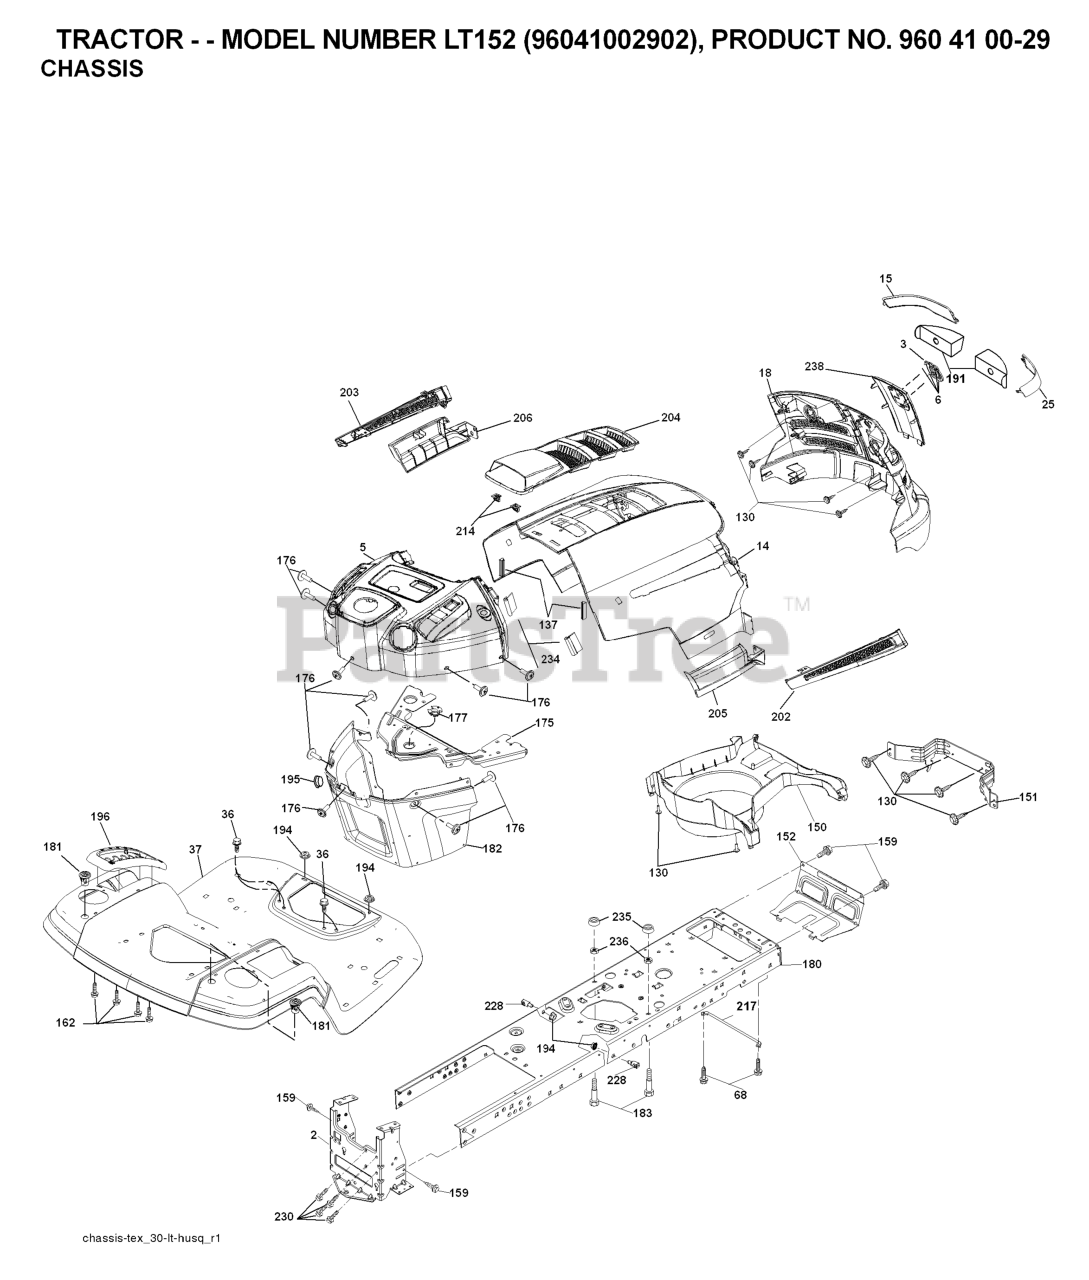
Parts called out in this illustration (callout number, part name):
2	DRAWBAR.1PC.NSTL
3	RP LOGO
5	DASH
14	HOOD
15	LENS.HUSQVARNA LT.LH
18	RP GRILLE/LENS ASM.
25	LENS.HUSQVARNA LT.RH
36	SCREW 5/16"
68	Screw 5/16-18 x 1/2 Hex, Self Tapping 5/16-18 x 1/2
130	SCREW
137	BUMPER DASH
151	BRACKET PIVOT
152	SHIELD.BROWNING/DEBRIS
159	SCREW, 3/8-16X3/4
162	SCREW.HI-LO.CONSOLE
175	CROSSMEMBER
176	SCREW.#10-24X5/8.RN.QU
177	BUSHING STEERING
180	CHASSIS.STAMPING.LT/GT
181	BUSHING.MNT.FEND.CRGO.
182	DASH LOWER
183	BOLT.5/16-18X1-1/4 FULL.THREAD
189	SCREW, 3/8-16X3/4
191	INSERT REFLECTIVE
194	NUT LOCK HEX FLANGE 5/16-18
195	PLUG DASH
196	CONSOLE.ASM.DECK.LIFT.
202	VENT SIDE HOOD RH
203	VENT SIDE HOOD LH
204	VENT TOP HOOD
205	SKIRT SIDE RH
206	SKIRT SIDE LH
214	CLIP.RETAINER.TINNER.
217	ROD.PIVOT.HOOD
228	STUD.FASTNER.W/ANTI-ROTATE
230	SHOULDER BOLT 5/16-18TT
234	BUMPER.HOOD.TEX.HUSQVARNA
235	SPACER FENDER
238	TRIM
